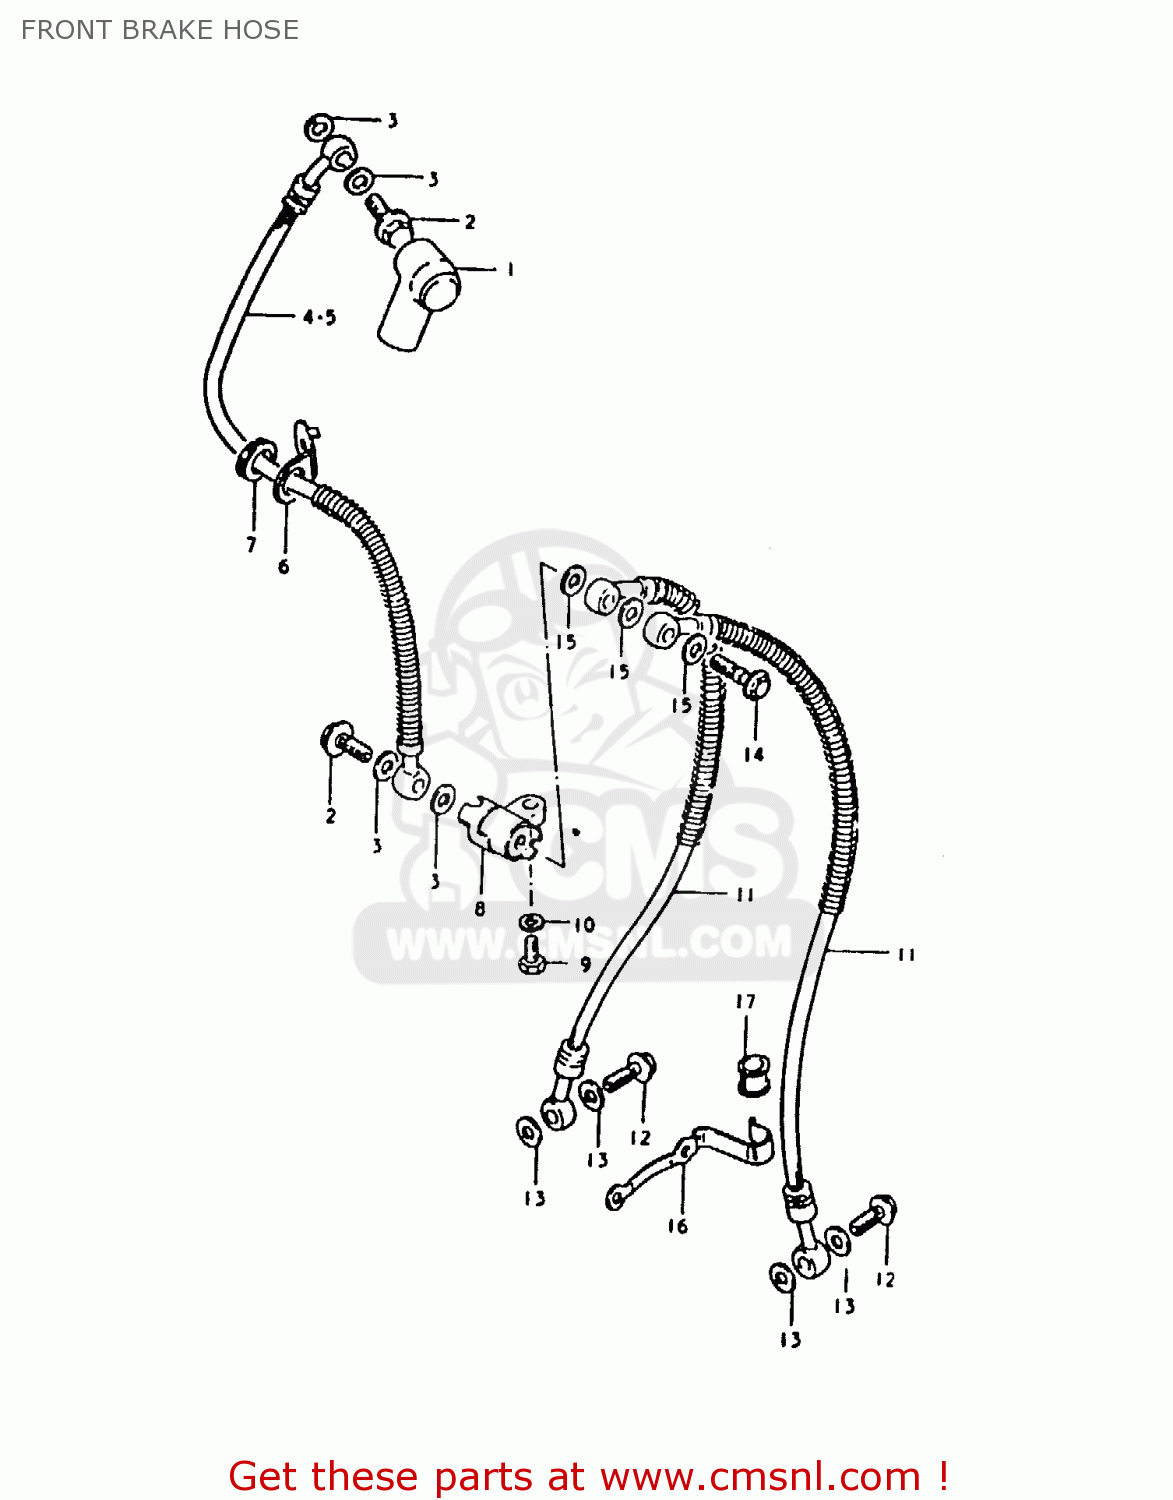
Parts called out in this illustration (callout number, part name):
1	BOOT,MASTER CYLINDER
2	BOLT,UNION
3	WASHER
4	HOSE,FRONT BRAKE
5	HOSE,FRONT BRAKE
6	GUIDE,BRAKE HOSE
7	GROMMET
8	JOINT,BRAKE HOSE
9	BOLT
10	LOCK WASHER
11	HOSE,FRONT BRAKE
12	BOLT,UNION
13	WASHER
14	BOLT,UNION
15	WASHER
16	GUIDE,FRONT BRAKE HOSE
17	BUSH,BRAKE HOSE GUIDE,NO.2
